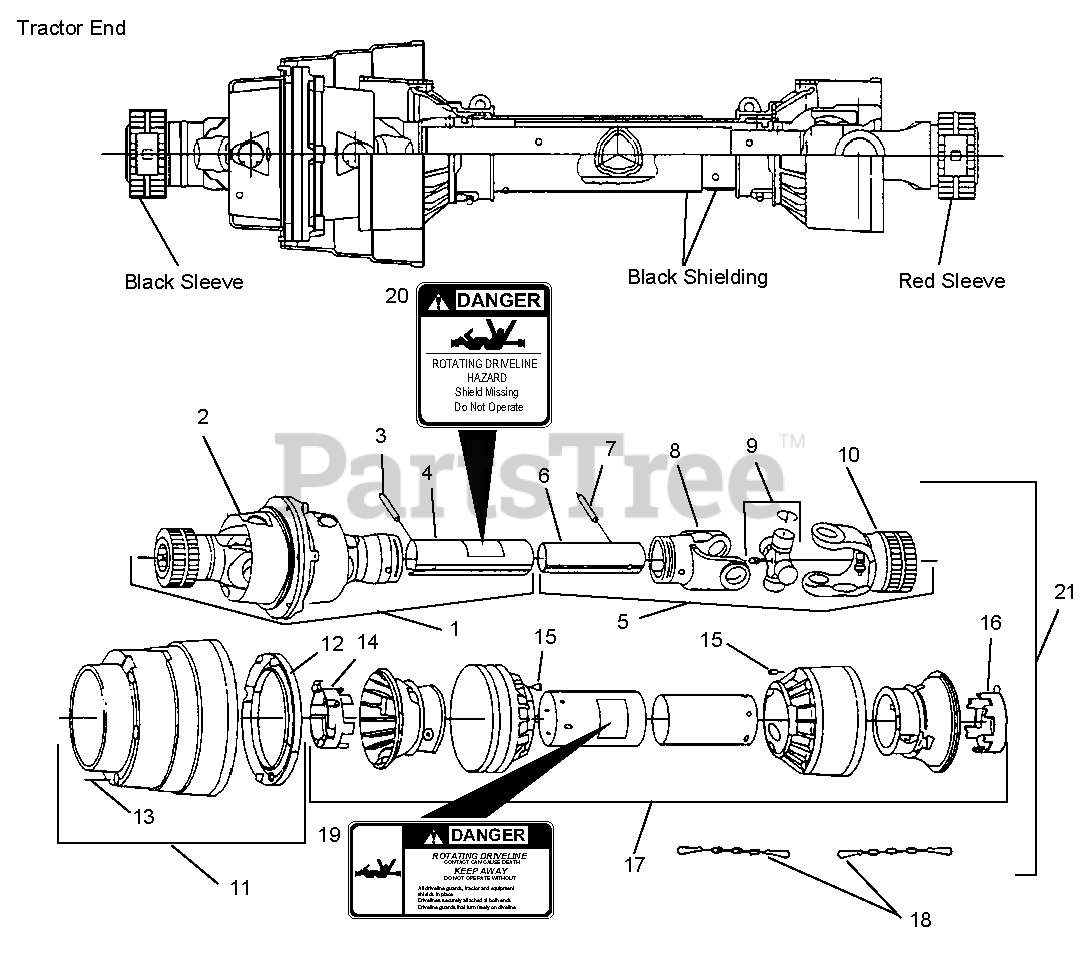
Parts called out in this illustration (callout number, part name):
2	Assembly, Constant Velocity Joint (Tractor End)
3	Pin, Roll 8 mm x 60 mm
4	Tube, Outer
6	Tube, Inner
7	Roll Pin 8 mm x 55 mm
8	Yoke, Inner Tube
9	Kit, Cross and Bearing
10	Assembly, Yoke (Implement End)
11	Shield, Wide Angle
12	Bearing, Soft Cone
13	Screw, Self-Tapping #6
14	Tube, Bearing Outer
15	Pin, Lock
16	Tube, Bearing Inner
17	Shield, Safety
18	Chain, Safety
19	Decal, Danger
20	Decal, Danger
21	DRIVELINE ASSEMBLY 50022104
